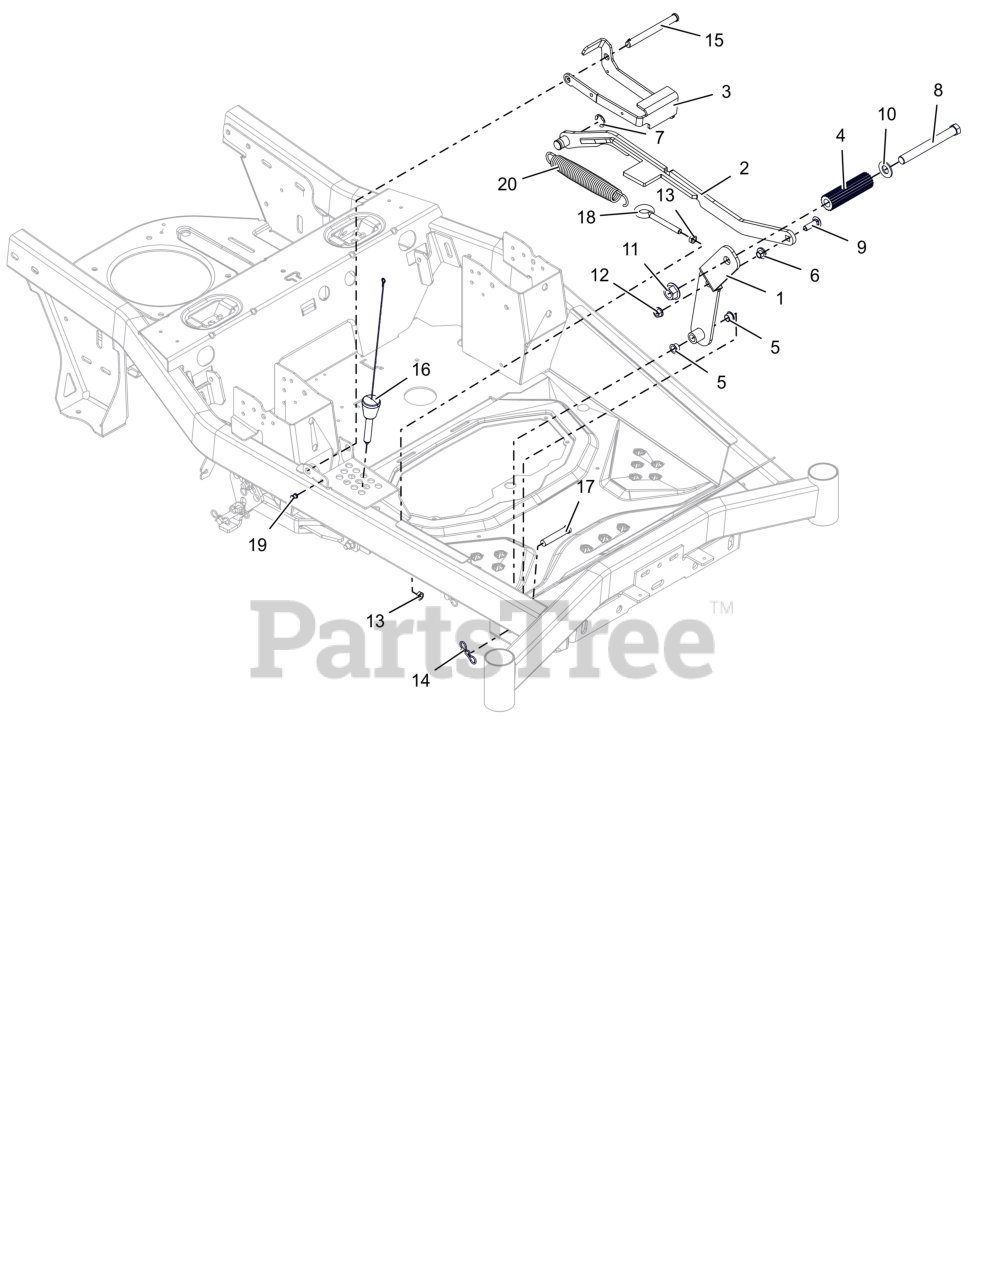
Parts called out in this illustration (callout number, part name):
1	WLDMT- FOOT PEDAL
2	LINK- DECK LIFT
3	WLDMT, TRANSPORT LOCK (BLACK)
4	ROD, FOOT PEDAL (BLACK)
5	BUSHING, POLYLINER-.50 SPLIT
6	BSHG-FLG .385X.500X.875X.406
7	RING, RETAINING-E .750X.050
8	BLT, HEX .62-11X5.50 G5 FBP
9	BLT,RHSSN .38-16X1.25 G5 ZCC
10	WSHRFLT 5/8SAE CARBHARD FBP
11	NUT,FLG-TOP LK .625-11 FBP
12	NUT-LK-CTR-FLG .375-16 GF ZCC
13	NUT-JAM .375-16 G2 ZCC
14	PIN, BOWTIE .091X1.875 ZCC
15	PIN, SLIC-.500X4.97X4.55 -ZC
16	PIN- MAGNETIC .50X2.70
17	PIN-CLEV .494X2.50 BRIGHT ZINC
18	BOLT,EYE .38-16X4.50,.75"EYE
19	POST, & SCREW, PUSH LOCK .25 X .25
20	SPRING- EXTENSION
